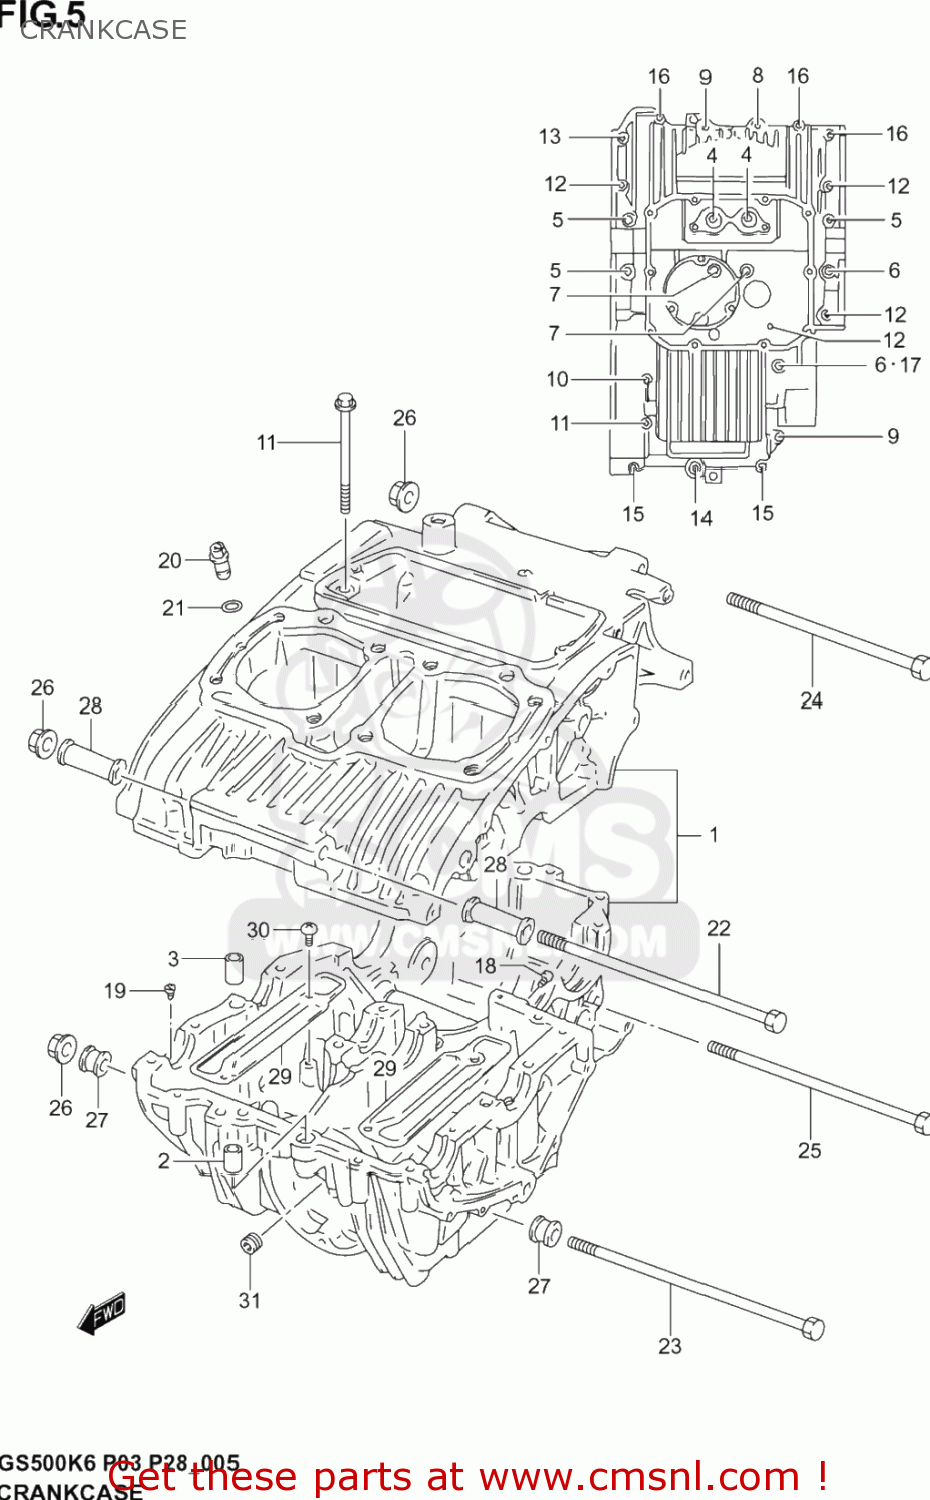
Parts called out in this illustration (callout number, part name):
1	CRANKCASE SET
2	PIN(10.4X13X22)
3	PIN(8.4X11X20)
4	BOLT
5	BOLT(8X125)
6	BOLT(8X110)
7	BOLT(8X100)
8	BOLT
9	BOLT
10	BOLT(6X125)
11	BOLT(6X105)
12	BOLT (6X90)
13	BOLT
14	BOLT
15	BOLT
16	BOLT (6X45)
17	GASKET(8.2X14X1) (NAS)
18	JET,AIR
19	JET
20	JET
21	O RING(D:1.05,ID:3.1)
22	BOLT(10X255)
23	BOLT(10X245)
24	BOLT(10X170)
25	BOLT(10X160)
26	NUT
27	SPACER,ENG MTG(L:16.8)
28	SPACER,ENGINE MOUNT(L:65)
29	PLATE,OIL SEPARATOR
30	BOLT(6X12)
31	JET,OIL PAN GALLERY
